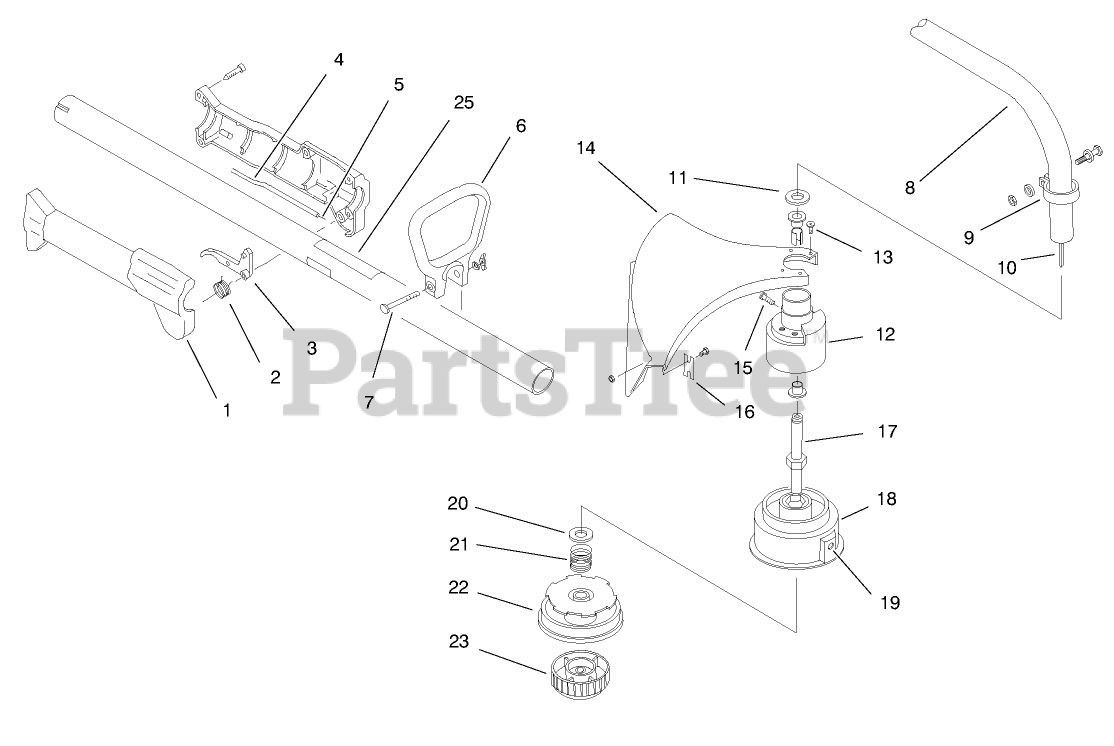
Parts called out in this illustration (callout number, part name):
1	Throttle Housing & Trigger Asm.
2	THROTTLE TRIGGER SPRING
3	TRIGGER - THROTTLE
4	HOUSING-CABLE
5	THROTTLE CABLE WIRE
6	D-HANDLE
7	HARDWARE - D-HANDLE
8	DRIVE SHAFT HSG ASM
9	CLAMP ASM - UPPER
10	Drive Shaft
12	BUSHING HSG ASM
13	GUARD MTG SCREW ASM
14	Guard and Blade Asm. (Incl. Ref. #16)
15	ANTI-ROTATION SCREW
16	BLADE ASM
17	Shaft-Spool
18	OUTER SPOOL EYELET ASM
19	EYELET
20	RETAINER ( 10 PACK)
21	SPRING
22	REEL - INNER
23	Assy.-Bump Head
25	Decal-Safety Symbol
